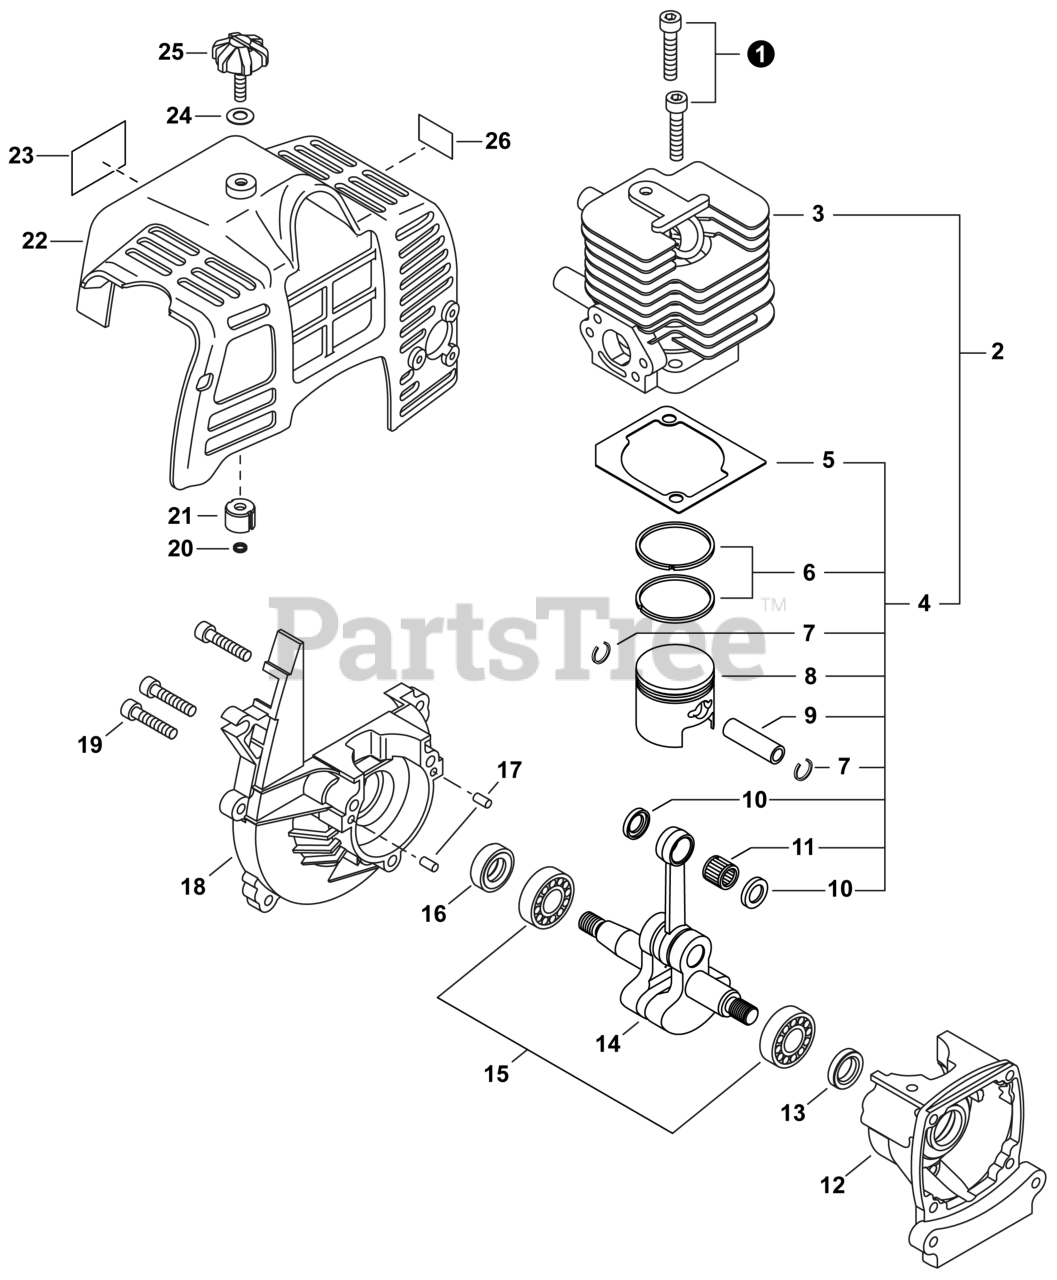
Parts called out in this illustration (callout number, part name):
1	BOLT 5×25
2	REPAIR KIT, ENGINE
3	CYLINDER
4	PISTON KIT
5	GASKET, CYLINDER
6	RING, PISTON
7	RING, SNAP
9	PIN, PISTON 8
10	WASHER, THRUST 8
11	BEARING, NEEDLE 8
12	CRANKCASE S
13	SEAL, OIL 12
14	CRANKSHAFT
15	BEARING, BALL 6001 C3
16	SEAL, OIL 12
17	PIN, LOCATING 4×8
18	CRANKCASE M
19	BOLT 5×25
21	INSULATOR 5 MM
22	COVER, ENGINE
23	LABEL - MODEL C230
24	WASHER, CONE M6
25	THUMBSCREW
26	LABEL - CAUTION - HOT
